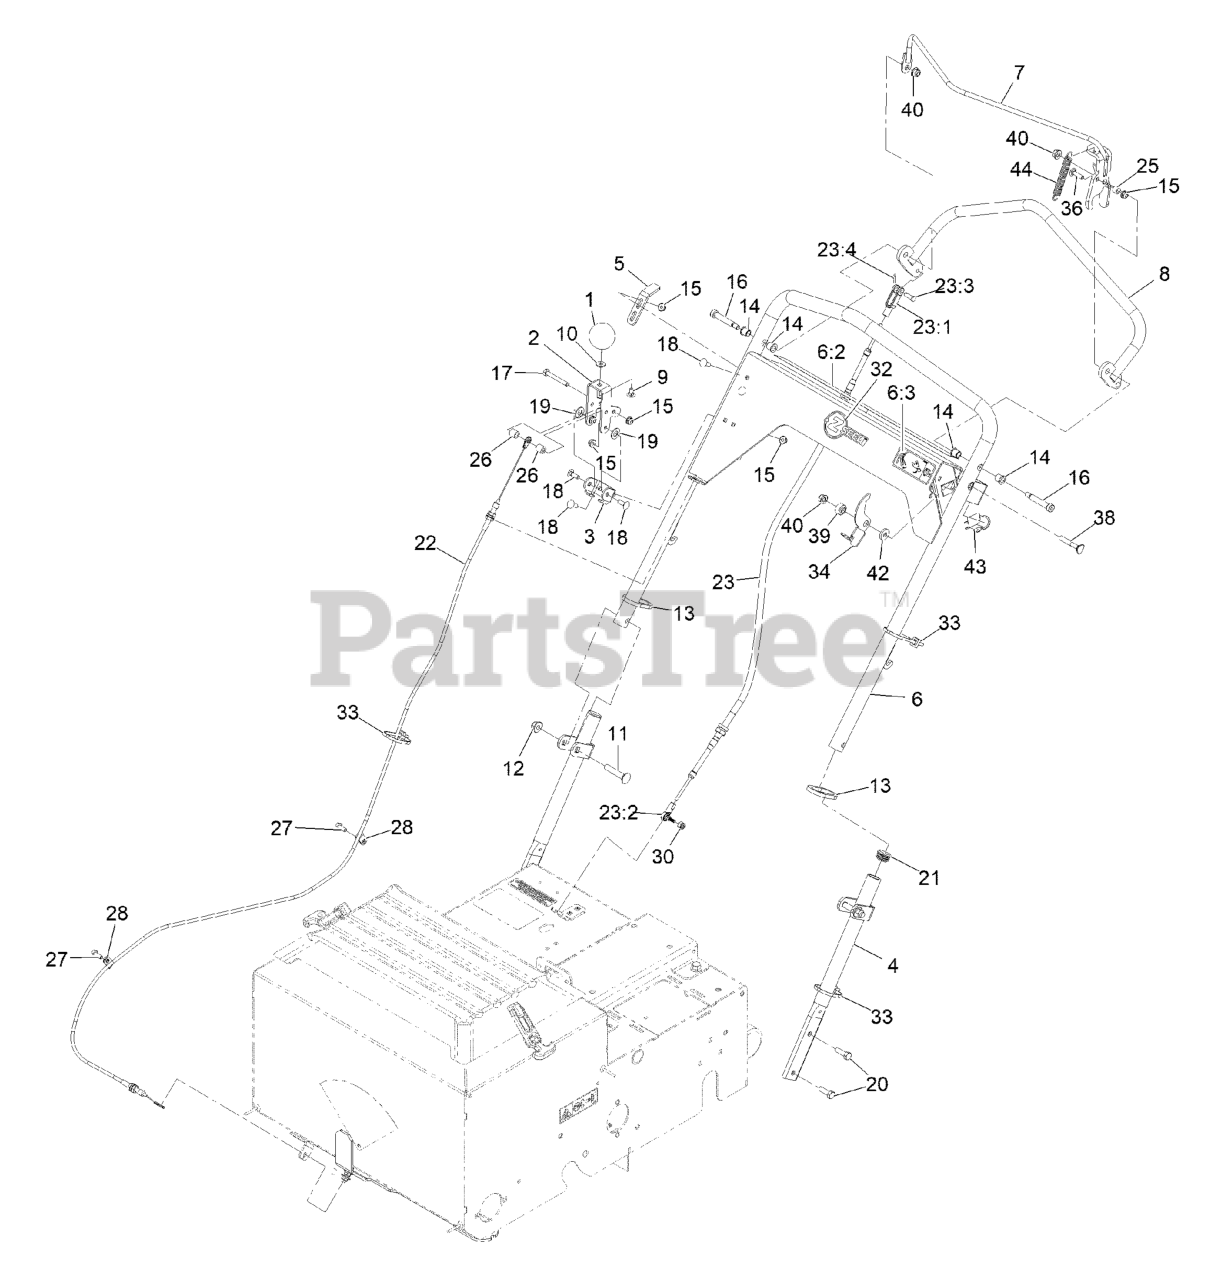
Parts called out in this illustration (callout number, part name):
1	KNOB-RATE, FLOW
2	LEVER-ADJUST, FLOW
3	BRACKET-ADJUST, FLOW
4	HANDLE-LOWER
5	BRACKET-ADJUST, DRIVE
6:2	DECAL-CONTROL PANEL, SEED
6:3	DECAL-SAFETY LATCH
7	BAIL-CLUTCH
8	DRIVE HANDLE WA
9	SCREW-CARR
10	WASHER-FLAT
11	SCREW-CARR
12	NUT-HF, NI
13	RING-HANDLE LOCK
14	BEARING
16	SCREW-SHOULDER
17	SCREW-HH
18	BOLT-CARR
19	WASHER-PLAIN
20	SCREW-HH
22	CABLE-FLOW, SEED
23	CABLE-PUSH PULL
23:2	Ball Joint
23:3	Pin-Clevis
23:4	PIN-COTTER
27	SCREW-HH
28	CLAMP-R
30	NUT-LOCK
32	DECAL-Z-SEED LOGO
33	TIE-CABLE
34	LATCH-BAIL
36	SCREW-CARR
39	BUSHING-STEPPED
40	NUT-HF, NI
42	WASHER-FLAT
43	SWITCH-BAIL
